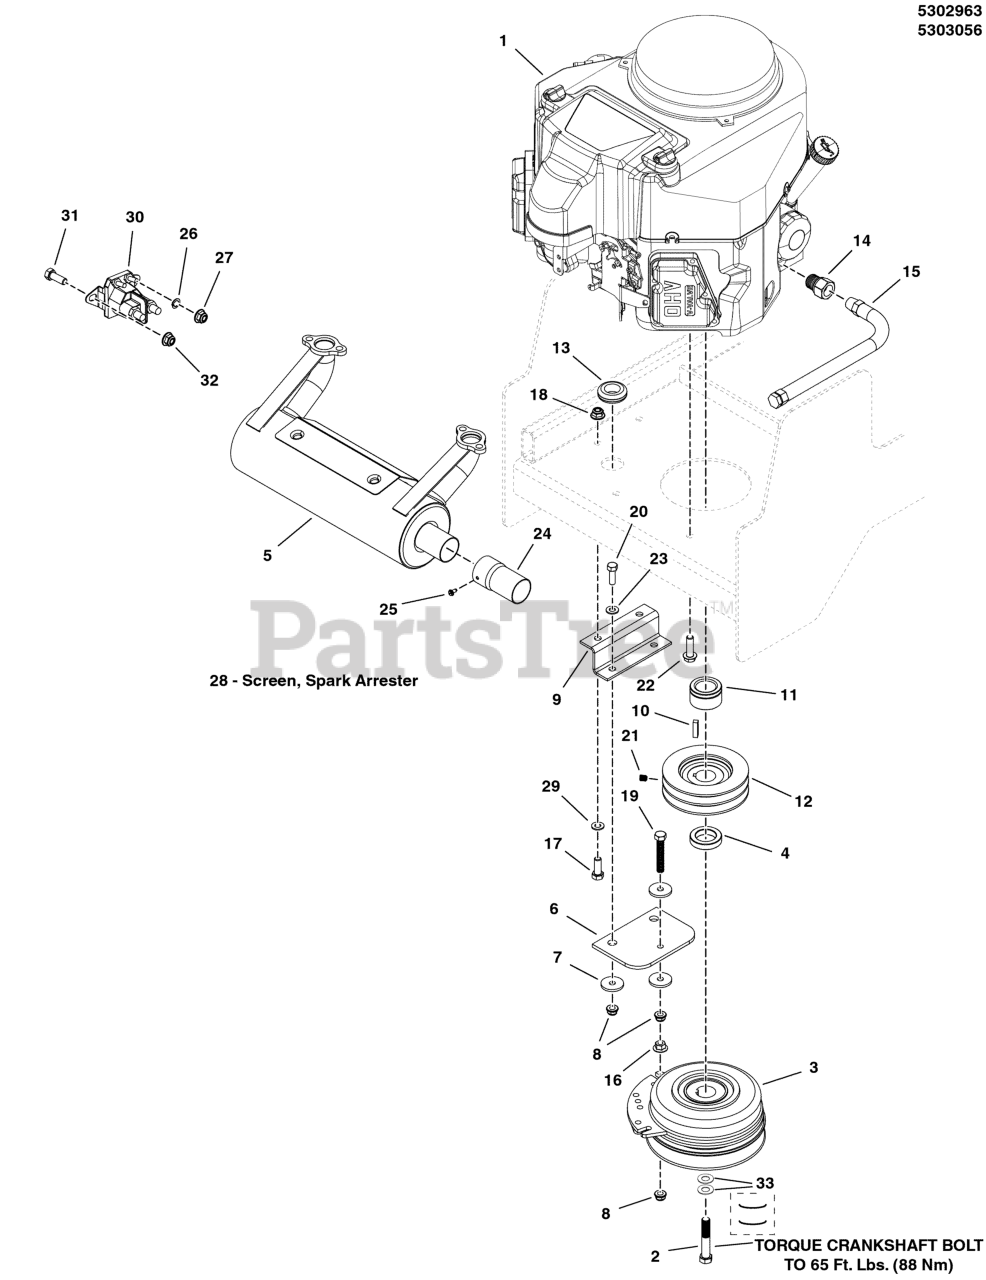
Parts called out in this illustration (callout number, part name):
1	ENGINE, KAWASAKI
2	BOLT, CRANKSHAFT,7/16-20X2-1/2, GD8
3	* CLUTCH, 5218-134, WARNER
4	SPACER, 1.13 X 1.75 X .38
5	MUFFLER, KAWASAKI
6	CLUTCH ANCHOR PAD
7	WASHER, .34 X 1.25 X 10 GA
8	NUT, 5/16-18 HEX NYLOCK FLANGE
9	ANCHOR, CLUTCH - BLK
10	KEY, 1/4 SQ X 1
11	SPACER, 1.13 X 1.75 X 1.03, CZ
12	PULLEY, CRANKSHAFT, 1.126 ID X 4.75 OD
13	GROMMET, 7/8
14	ADAPTER-OIL DRAIN
15	HOSE, OIL DRAIN
16	NUT, 5/16-18 HEX SERRATED FLANGE (LARGE)
17	BOLT, 3/8-16 X 1" GD5 CZ
18	NUT, 3/8-16 HEX NYLOCK FLANGE
19	BOLT, 5/16-18 X 2-1/2 GD5 TFL, CZ
20	BOLT, 5/16-18 X 1 GD5 YZ
21	SET SCREW, 5/16-18 X 3/8, KNURL
22	BOLT,HEX FLG,SER GD5 3/8-16X1-1/4PACH CZ
23	WASHER, 5/16" SAE
24	EXTENSION, TAILPIPE, 3" - BLACK
25	SCREW,SELF-TAP,#8-32 X 3/8,WASH HEX, CZ
26	WASHER, 5/16 LIGHT LOCK
27	NUT, 5/16-24 JAM
29	WASHER, 3/8 SAE
30	SOLENOID-4 POLE 12 VOLT DC (TROMBETTA)
31	BOLT, 1/4-20 X 3/4 GD5 YZ
32	NUT, 1/4-20 HEX SERR. FLANGE
33	BELLEVILLE WASHER 1.1875 X .442 X .089
